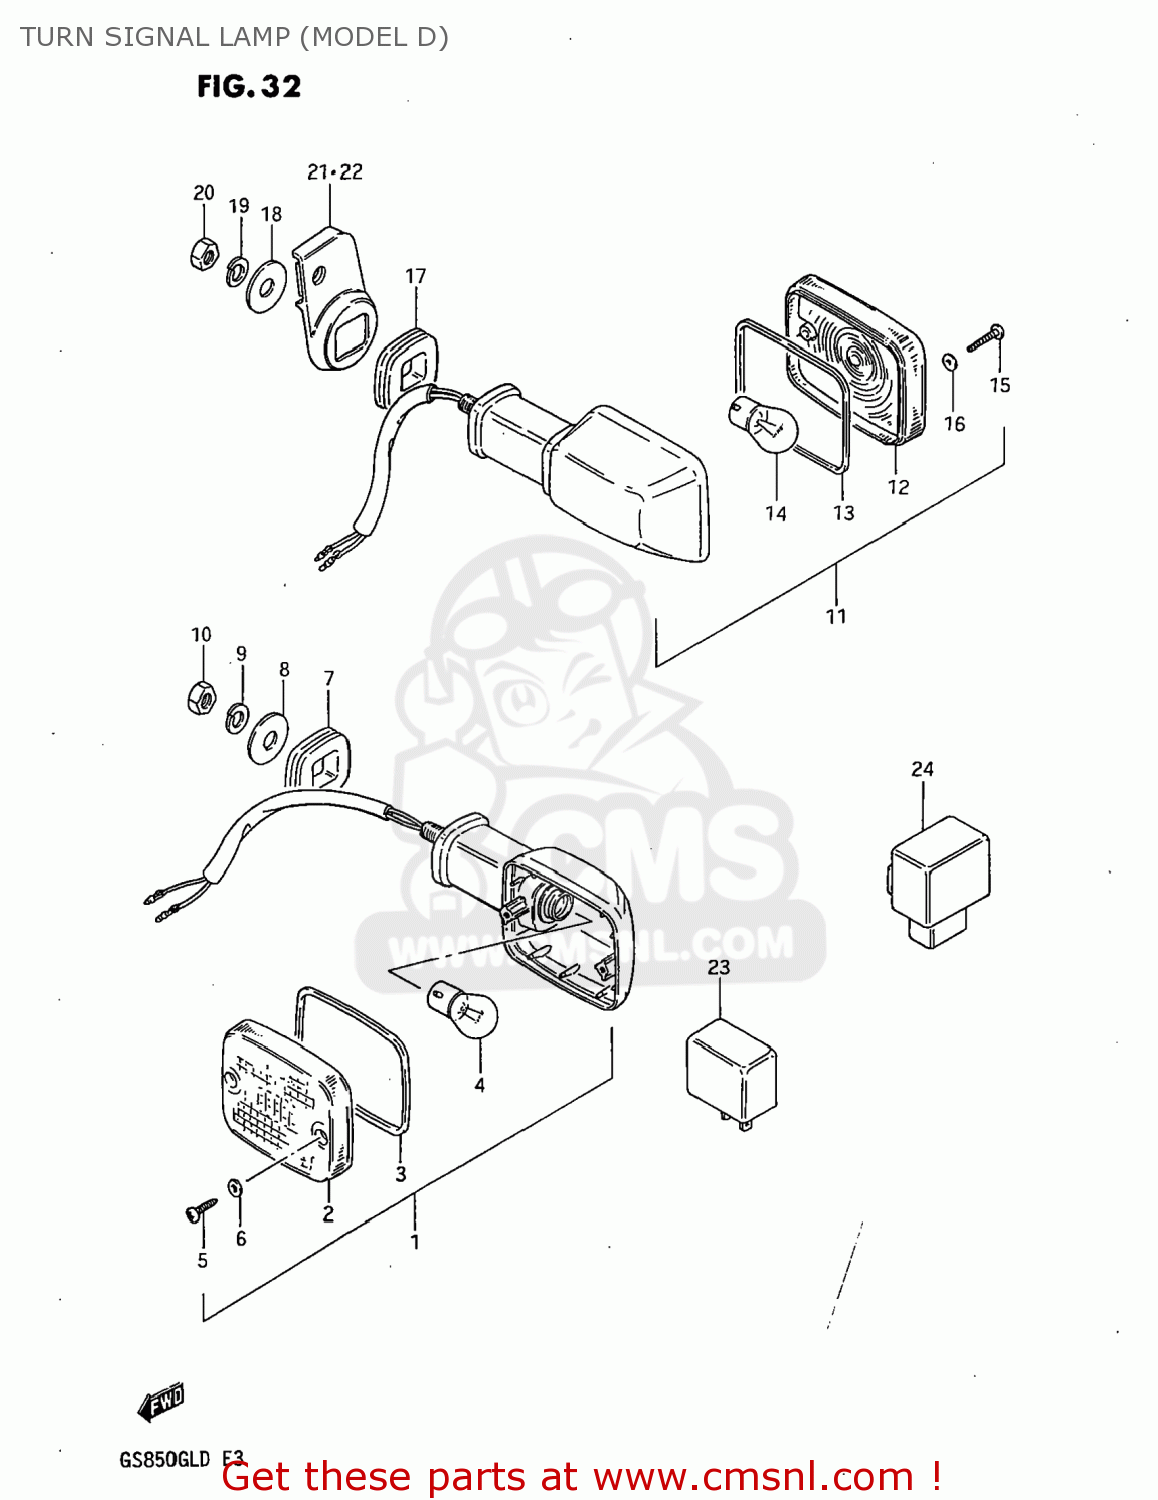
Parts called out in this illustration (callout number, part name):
1	LAMP ASSEMBLY,FRONT TURN SIGNAL
2	LENS
3	GASKET (NAS)
4	BULB(12V23W,STANLEY,A4577A)
5	SCREW
6	GASKET (NAS)
7	CUSHION
8	WASHER (10.5X30X2.3)
9	LOCK WASHER
10	NUT
11	LAMP ASSEMBLY,REAR TURN SIGNAL
12	LENS
13	GASKET (NAS)
14	BULB(12V23W,STANLEY,A4577A)
15	SCREW
16	GASKET (NAS)
17	CUSHION
18	WASHER (10.5X30X2.3)
19	LOCK WASHER
20	NUT
21	BRACKET,REAR TURN SIGNAL
22	BRACKET,REAR TURN SIGNAL
23	RELAY ASSY,TURNSIGNAL
24	UNIT,TURN SIGNAL CONTROL
